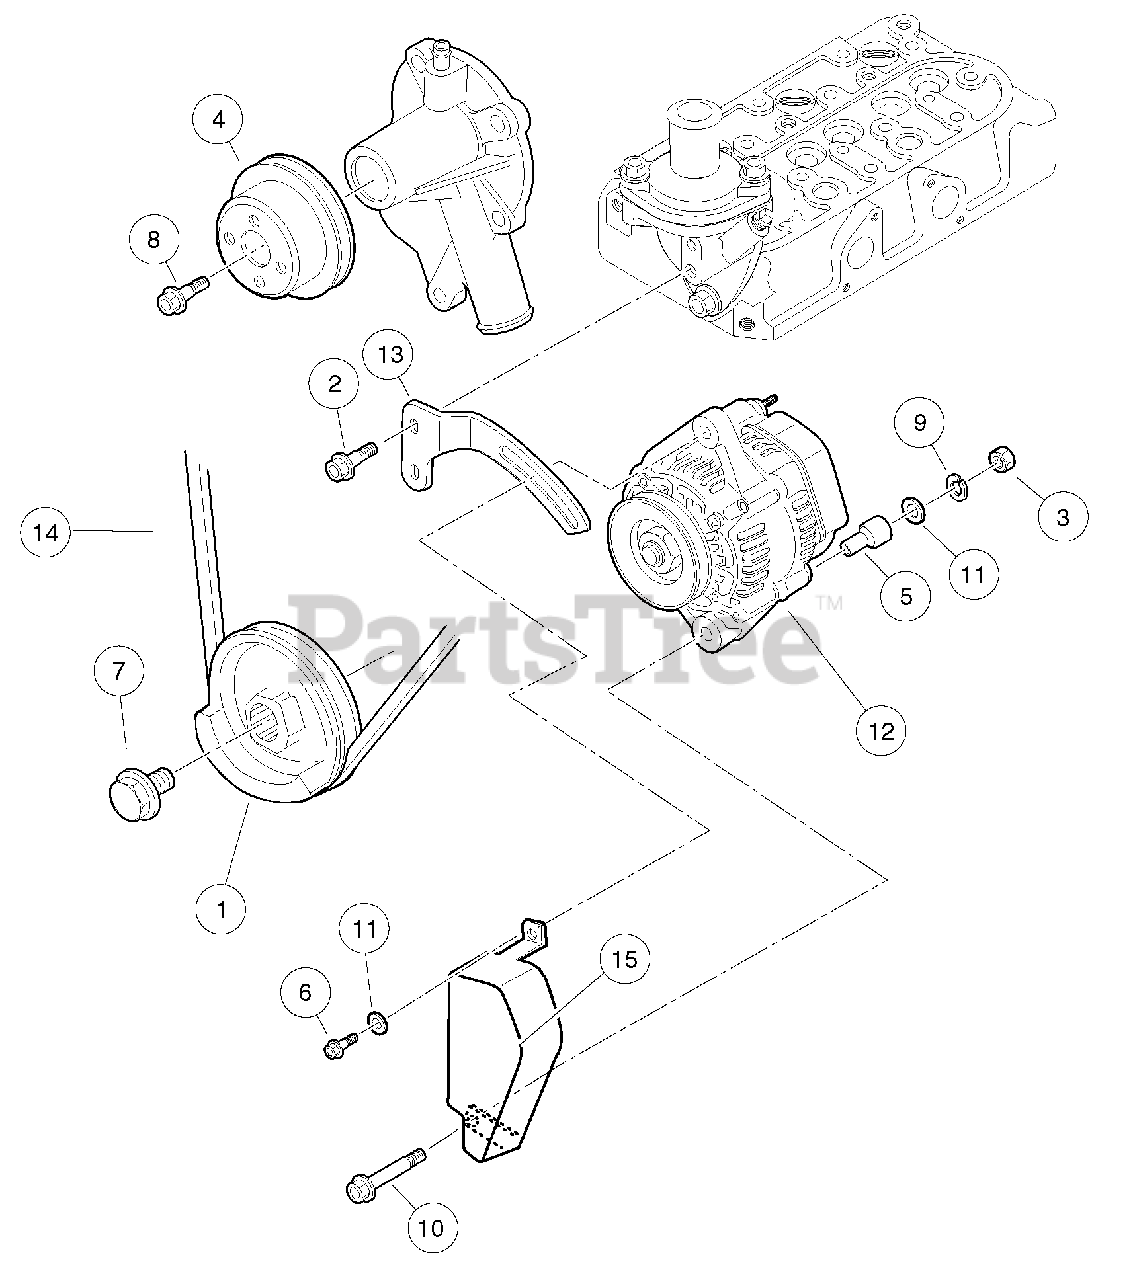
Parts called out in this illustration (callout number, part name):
1	Pulley, Fan Drive
2	Bolt, M6 X 1 X 20
3	Nut, M8, Plate
4	Pulley, Water Pump
5	Collar, Alternator Assy, D722
6	Bolt, Alt, D722, Adjuster
7	Bolt, Alt, D722, Drive Pulley
8	Bolt, D722, Drive Pulley
9	Washer, Spring, D722, Starter
10	Bolt, Alternator, Lower
11	Washer, Alternator, Upper
12	Alternator, 60 Amp
13	Brkt, Alt, D722, 60 Amp
14	Belt, Acc Drive, D722, 60 Amp
15	Guard, Acc Belt
